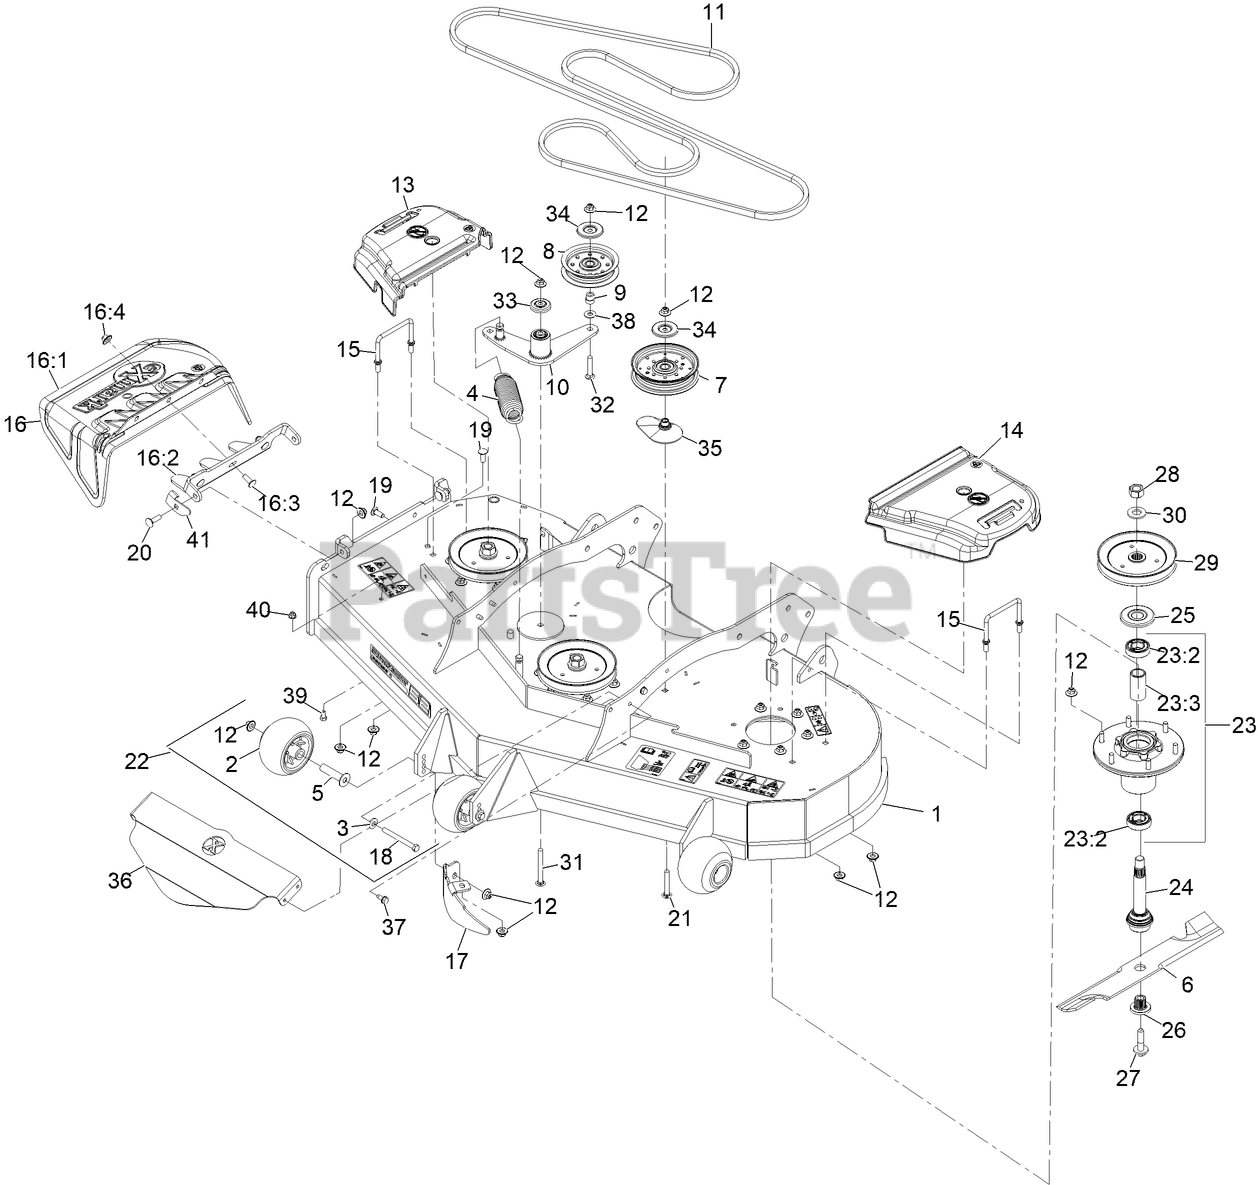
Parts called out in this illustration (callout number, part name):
1	ASM-DECK W/DECALS 524
2	ROLLER-SCALP, ANTI
3	WASHER-BELLEVILLE
4	SPRING-EXTENSION
5	AXLE, ROLLER
7	PULLEY-IDLER, FLAT
9	BUSHING,IDLER
10	IDLER ARM ASM W/BEARINGS
12	Nut-Nyloc 3/8-16 Flg
13	COVER-BELT, RH
14	COVER-BELT, LH
15	WIREFORM-COVER
16	ASM,DISCHARGE CHUTE
16:1	CHUTE,DISCHARGE
16:2	BRACKET,DISCHARGE CHUTE
16:3	SCREW-CARR
16:4	Nut-Nyloc 3/8-16 Flg
17	BAFFLE-DOGLEG, LZ-VT52
18	SCREW-HH 3/8-16 X 3 3/4 GR 8
19	SCREW-CARR
20	BOLT-CARR
21	SCREW-CARR
22	KIT, ANTI-SCALP ROLLER
23	ASM-CUTTER HSG WITH BEARINGS
23:2	BEARING-BALL
23:3	SPACER-BEARING
24	ASM-SPINDLE AND SEAL
25	GUARD,BEARING TOP .989
26	BUSHING,SPLINED
27	SCREW,SEMS 1/2-20 X 2.19
28	NUT-HEX
29	SHEAVE,BLADE DRIVE 6.50
31	SCREW-CARR
32	SCREW-CARR
33	GUARD-TOP
34	SHIELD-DUST
35	SPACER-PULLEY
36	Guard-Front Deck
37	SCREW-THD ROLL, HWH
38	WASHER-FLAT
39	SCREW-HH
40	NUT-HF, NI
41	STOP-DISCHARGE CHUTE
